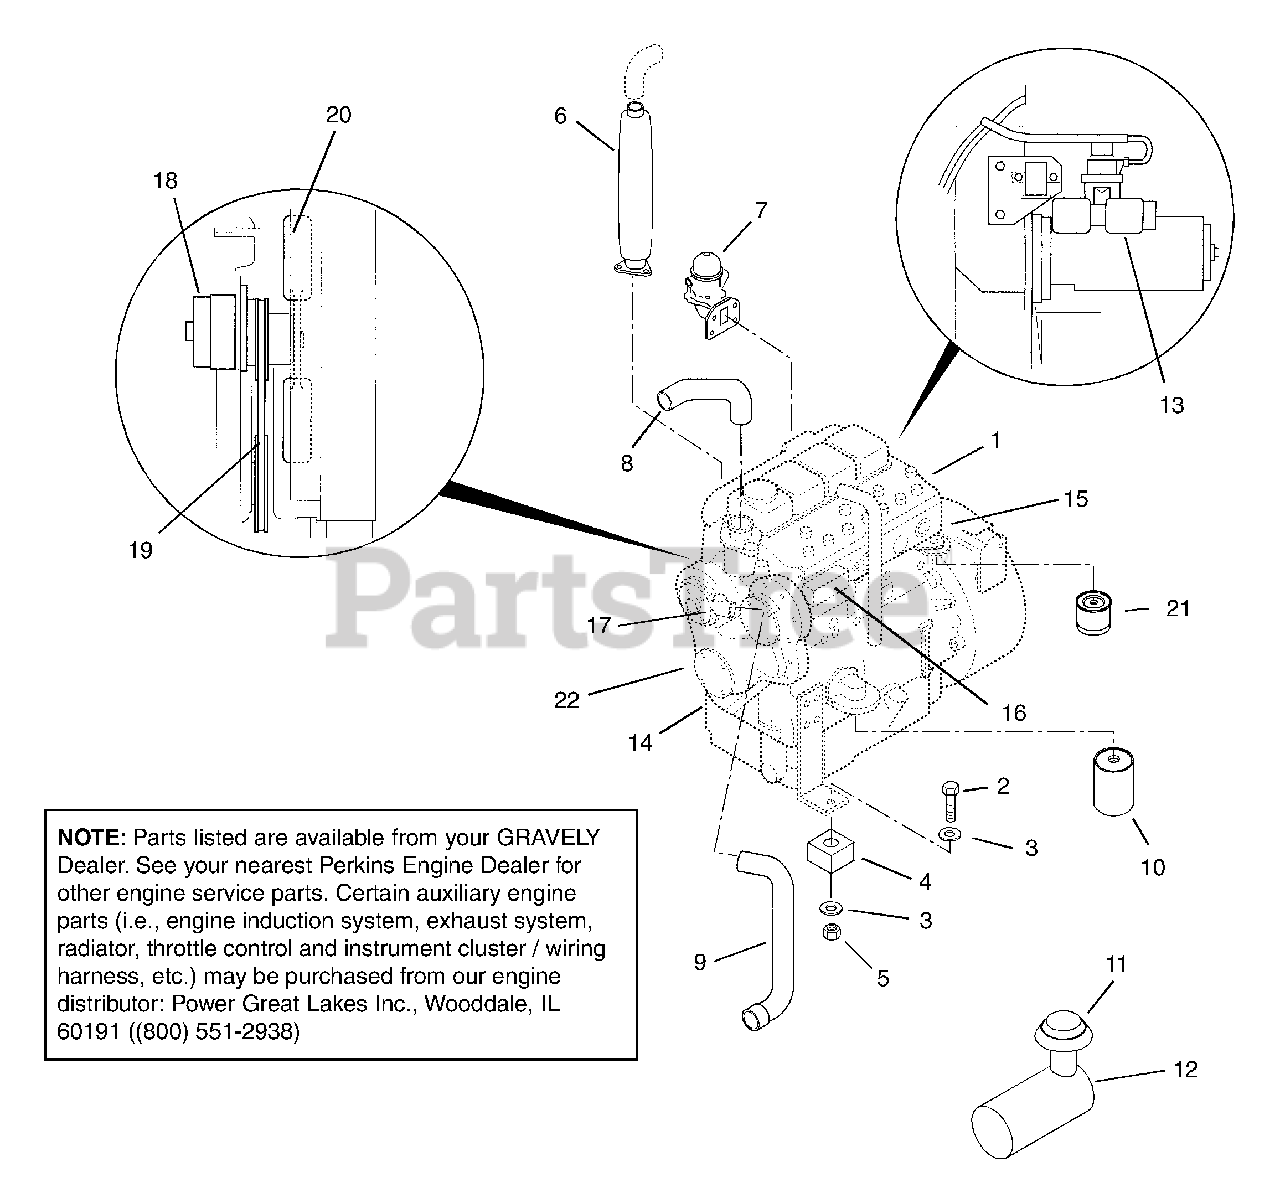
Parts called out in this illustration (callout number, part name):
1	Engine-Perkins 4.236 81 HP
1	Engine-Perkins T4.236 99 HP
1	Engine-Perkins Fastram 108 HP
2	Bolt-Hex .75-10 x 3.00 Grade 5
3	Washer-Flat-Steel .813 x 2.000 x .148
4	Engine Base Spacer
5	Nut-Locking-Center .75-10
6	Muffler
7	Pump-Lift
8	Hose-Radiator-Top
9	Hose-Radiator-Bottom
10	Filter-Oil
11	Filter-Air-Primary
12	Filter-Air-Secondary
13	Starter
14	Gasket Kit-Bottom
15	Gasket Kit-Top
16	Pump-Injection
17	Pump-Water
18	Alternator
19	Belt
20	Fan
21	Element-Fuel Filter
22	Pump-Oil
